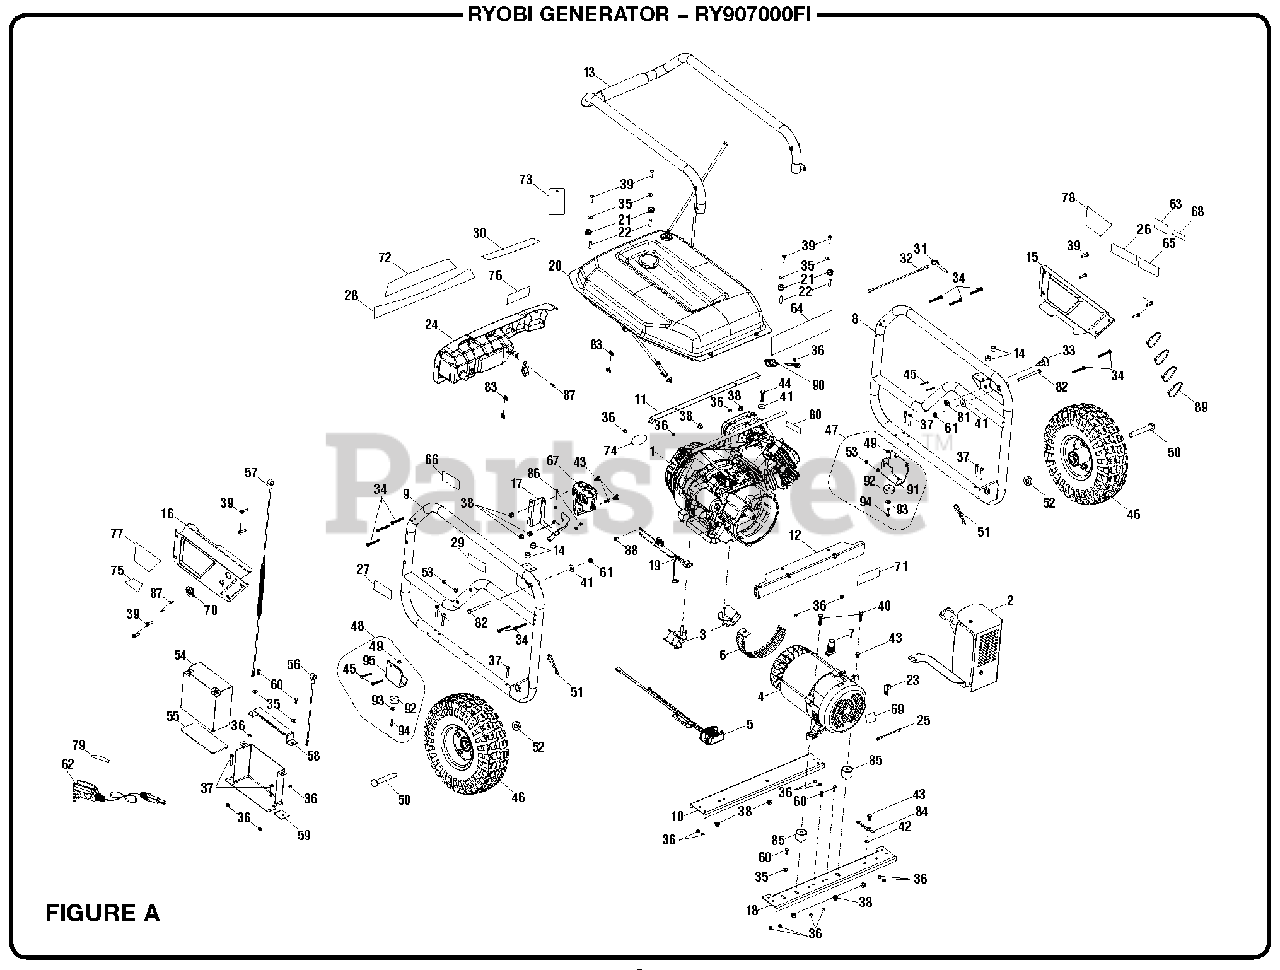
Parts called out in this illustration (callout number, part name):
1	Engine (R420 EFI)
2	Muffler Assembly
4	Generator Head Assembly (See Figure B)
5	Ac To Dc Regulator
6	Genhead Fan Cover
7	Rubber boot
8	Frame Assembly (Left)
9	Frame Assembly (Right)
10	Cross Member
11	Fuel Tank Support (Front)
12	Fuel Tank Support (Rear)
13	Handle Assembly
14	Handle Bumper
15	Panel (Left)
16	Panel (Right)
17	Fuel Pump Mounting Bracket
18	Cross Member
19	Battery Storage Charger Wire Harness
20	Fuel System
21	Fuel Tank Bushing
22	Fuel Tank Isolator
23	Ground Lug (1/4-20)
24	Electrical Panel
25	Bonding Wire
26	Hot Surface Label
27	Lubricant Label
28	Performance Label
29	Lock Pin Label
30	Quick Start Label
31	Release Pin
33	Handle Lock Assembly
34	Bolt (M6 x 50 mm, T30 Torx Pan Hd.)
35	Washer (M6)
36	Lock Nut (M6)
37	Bolt (M8 x 42 mm, Torx Pan Hd.)
38	Lock Nut (M8)
39	Bolt (M6 x 25 mm, Torx Pan Hd.)
40	Bolt (M8 x 35 mm, Hex Hd.)
41	Washer (M8)
42	Star Washer (M8)
43	Bolt (M8 x 15 mm, Hex Hd.)
44	Bolt (M8 x 40 mm, Hex Hd.)
45	Bolt (M6 x 48 mm, Pan Hd.)
47	Foot (Left)
48	Foot (right)
51	Hitch Pin
52	Washer (5/8)
53	Nut (M6 x 1 mm)
55	Battery Tray Gasket
56	Battery Cable (Red)
57	Battery Cable (Black 390 mm)
58	Battery Bracket
59	Battery Tray
60	Bolt (M6 x 16 mm, Hex hd.)
61	Nut (5/16-18 mm)
62	Battery Charger
63	Inquires Label
64	Combustion Warning Label
65	Fire Distance Label
66	Fire Danger Label
67	Returnless Fuel Pump
68	Pull Pin Label
69	Ground Label
70	Fuel Valve Bezel
71	Ground Warning Label
72	Logo Label
73	Notice Hangtag
74	Recoil Label
75	Charge Cable Label
76	EFI Logo Label (Front)
77	EFI Logo Label (Right)
78	EFI Logo Label (Left)
79	Battery Maintainer Label
80	Throttle Body EFI Logo Label
81	Lock Nut (1/2-20)
82	Handle Pivot Pin
83	U-Clip (M6)
84	Ground Wire
85	Isolator Generation 7
87	Screw (M4 x 12 mm, T20 Torx Pan Hd.)
88	Bolt (M5 x 10 mm, Hex Hd.)
90	O2 Sensor
91	Foot Tall Bracket (Left)
93	Washer (1/4)
94	Bolt (M6 x 20 mm, Hex Hd.)
95	Foot Tall Bracket (Right)
